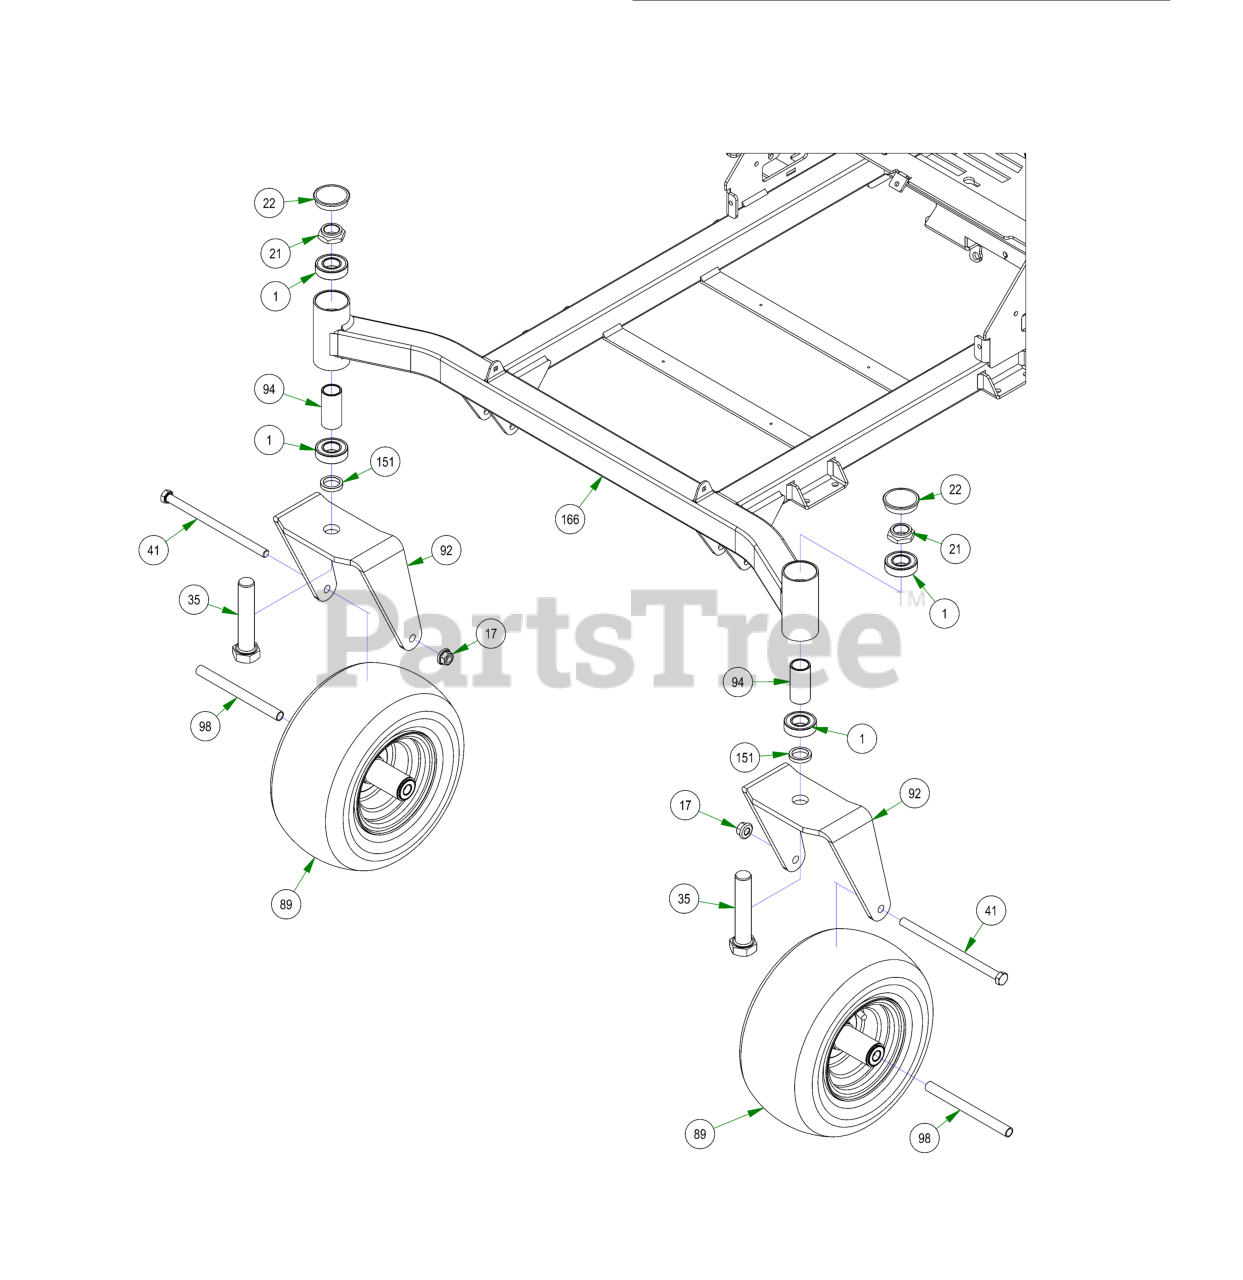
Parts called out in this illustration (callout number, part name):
1	1641 BEARING W/2 CONTACT RUBBER SEALS
17	1/2-13 NYLON INSERT FLANGE LOCKNUT ZINC
21	1"-14 NYLON INSERT JAM LOCKNUT ZINC
22	2017 Bearing Cover
35	1"-14 X 5 HEX CAP SCREW (GR.8) ZINC YELLOW
41	1/2-13 X 8-1/2 HEX CAP SCREW (GR.5) ZINC
89	12x6x6 Front Tire & Black Wheel Assembly (Representation Only)
92	2017 ZT Front Fork
94	2016 Front Bearing Spacer
98	Front Wheel Spanner
151	1.02 ID X 1.38 OD X .250 THK SPACER ZINC
166	2022 MZ/ZT 54"-60" Frame
